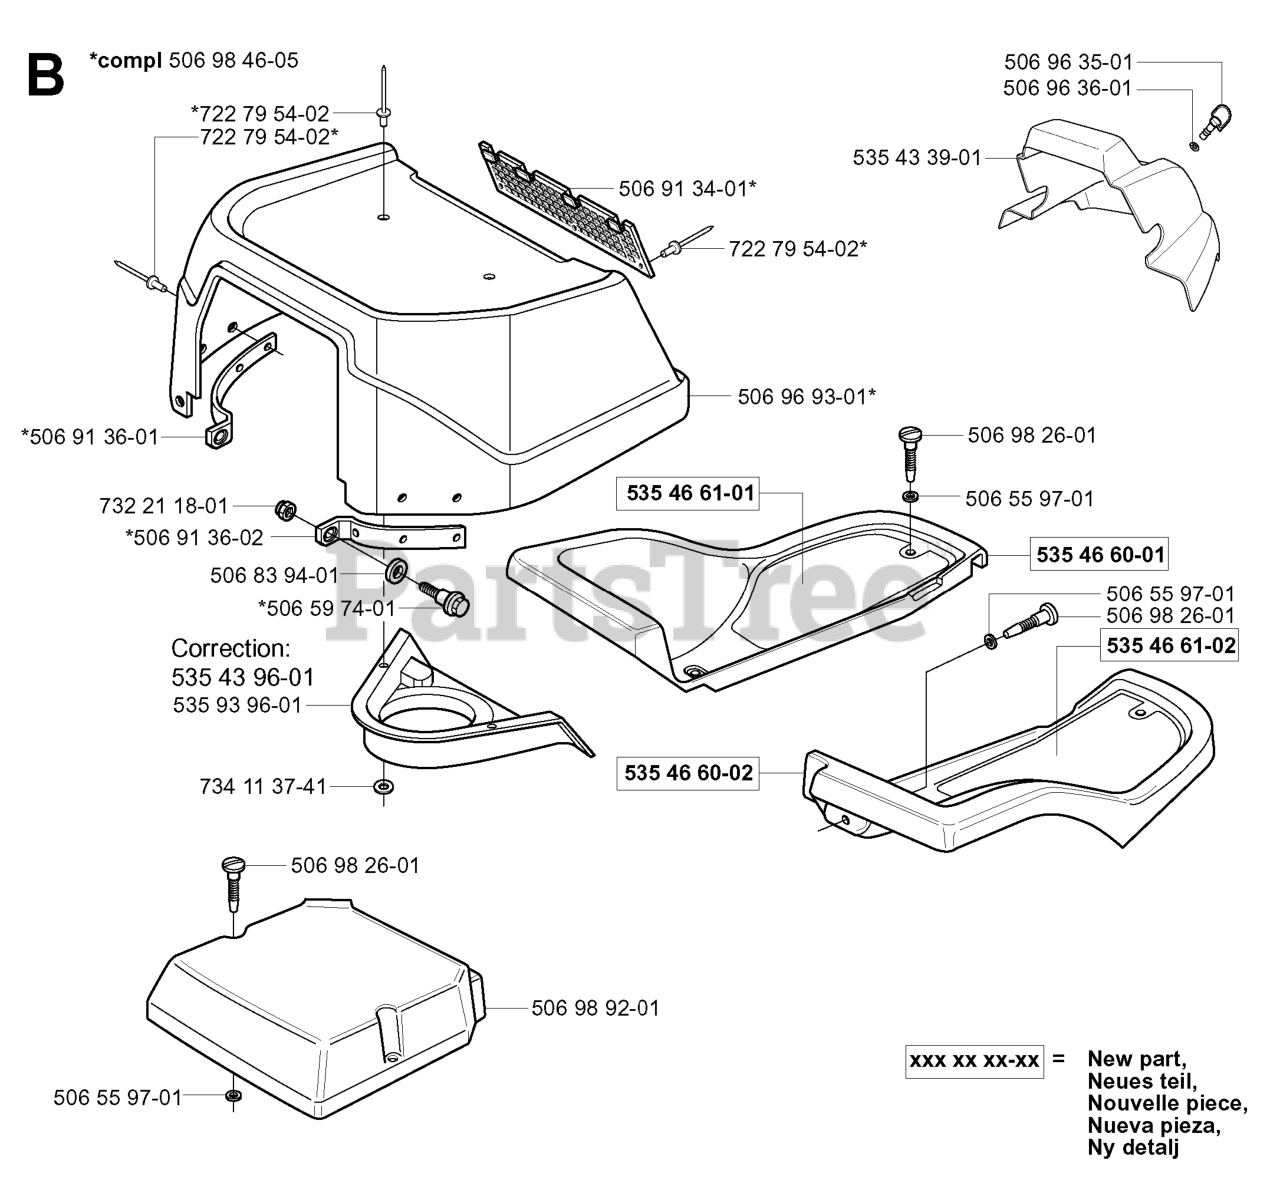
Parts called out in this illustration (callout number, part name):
150	COVER, BELT 2CY
151	SCREW, 10-24X.38 SLHWATAP
170	COVER, TOP
171	SCREW, #10-24X.63 TRPHTAP
173	SCREW, #10-14 X .63
174	WASHER, FLAT .250X .56X.
184	NUT, TINN "U" TYPE
190	GROMMET & WASHER
191	KNOB, PLASTIC
203	2 KEYS & RING
211	HOSE,PRIMER 5.75 TEC
212	NUT, 1/4-20 HEX KEPS
220	BRACKET, SHROUD MNTG
221	SCREW, #10-24 X .63 TRPHTAP
230	DOOR, ACCESS
232	SCREW #10-16 X .75
